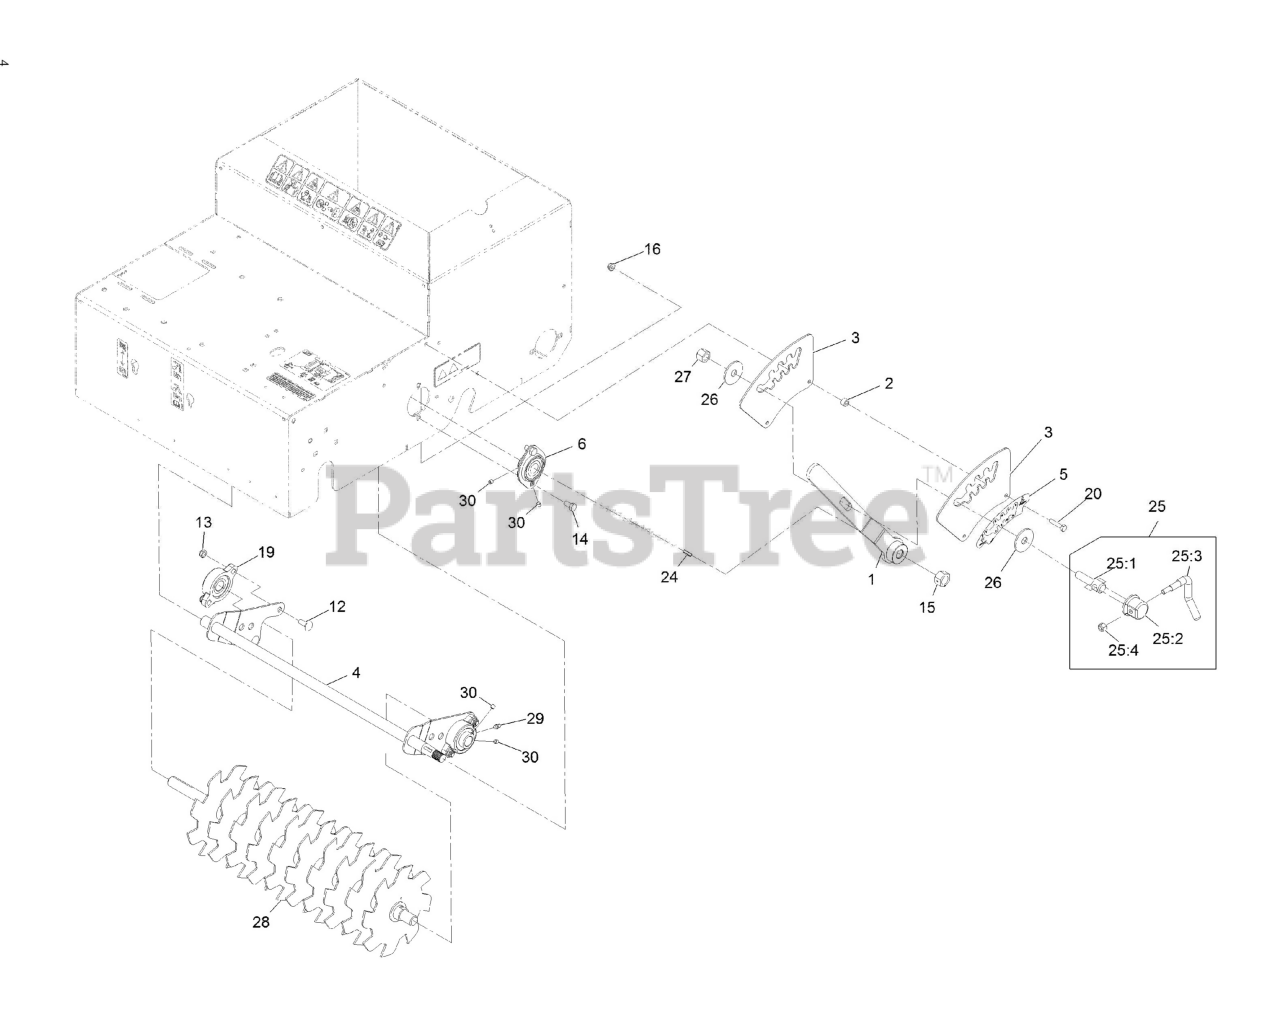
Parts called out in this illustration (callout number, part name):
1	HANDLE-HEIGHT
3	PLATE-HEIGHT
4	PIVOT-HEIGHT
5	DECAL-CUT DEPTH, SLICER/S
6	BEARING
12	SCREW-CARR
13	NUT-LOCK, NI
14	SCREW-HH
15	NUT-BLADE
19	BEARING-FLANGE
20	SCREW-HH
24	KEY-WOODRUFF
25	LEVER ASM
25:1	SCREW-LOCK
25:2	CAP-LOCK
25:4	NUT-LOCK, NI
26	WASHER-THRUST
27	NUT-LOCK, NI
28	SLICER SHAFT ASM
29	FITTING-GREASE
30	SCREW-SET, HSH
